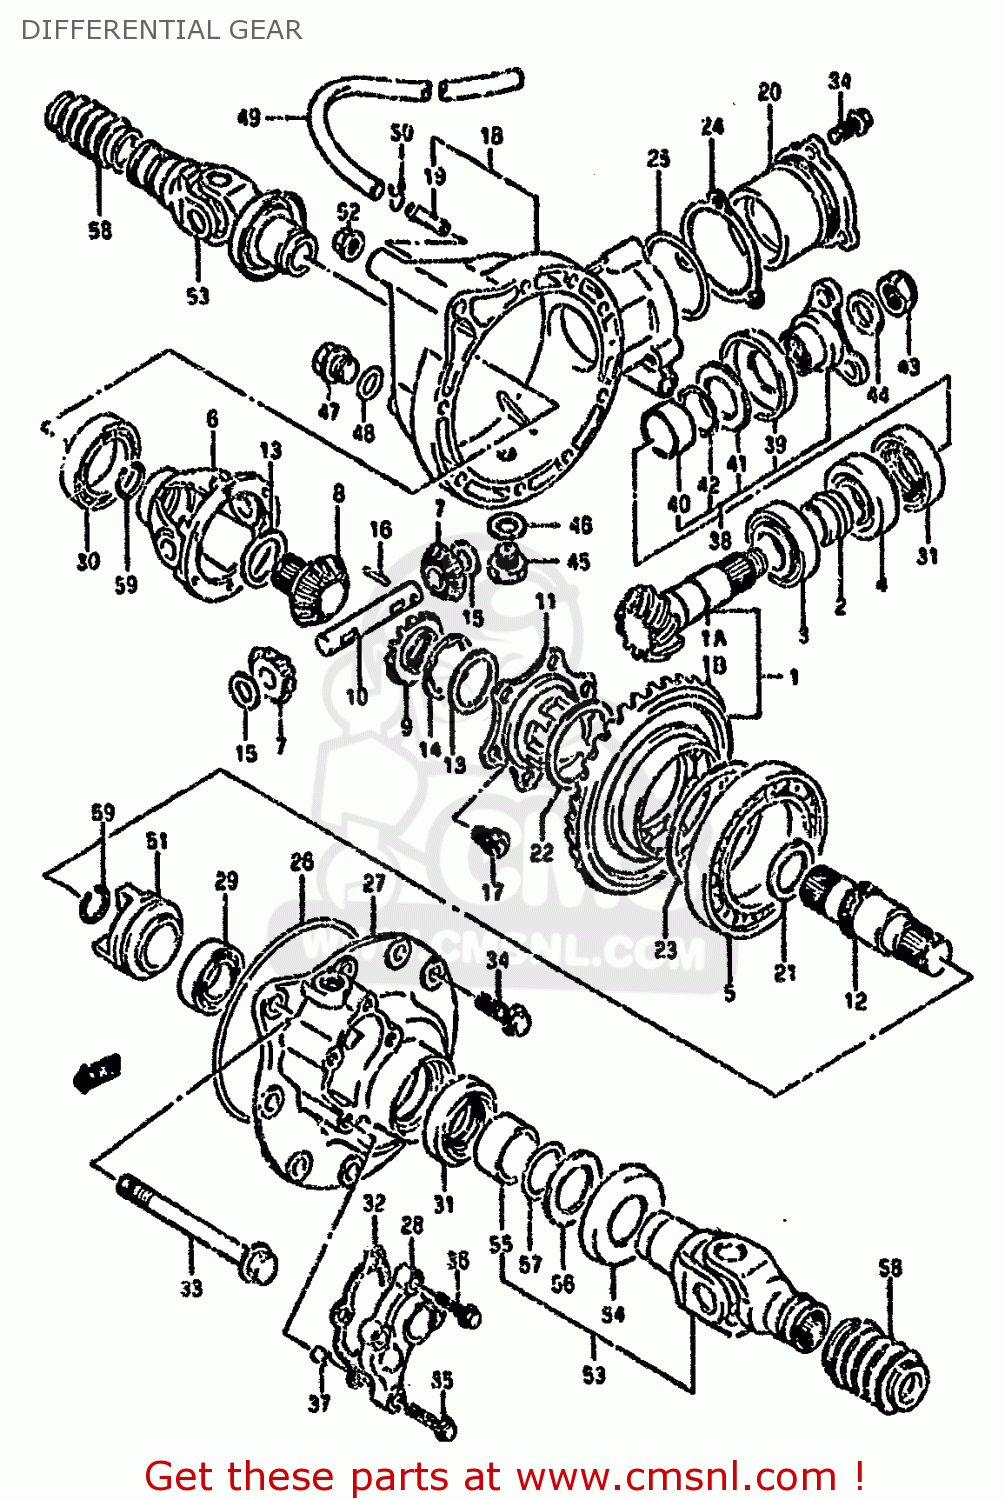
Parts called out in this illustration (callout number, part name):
1	GEAR SET,FINAL BEVEL
1A	GEAR,FINAL DRIVE BEVEL
1B	GEAR,FR DRIVEN BEVEL
2	SPACER(25.3X28X28)
3	BEARING(25X52X19.25)
4	BEARING(25X52X16.25)
5	BEARING(70X110X13)
6	CASE,FR DIFFERENTIAL
7	PINION,DIFFERENTIAL SIDE
8	GEAR,FR DIFFERENTIAL
9	GEAR,RR DIFF
10	SHAFT,PINION
11	HUB,FR DRIVEN BEVEL GEAR
12	SHAFT,FRONT DRIVEN OUTPUT
13	WASHER(29X40X1)
14	WASHER
15	WASHER(13.3X25X0.85)
16	PIN(6X30)
17	BOLT
18	HOUSING,FRONT DIFFERENTIAL GEAR
19	UNION
20	HOUSING,FR DRIVE BEVEL GR
21	WASHER
22	SHIM,FRONT DRIVEN BEVEL GEAR
23	SHIM,DRIVEN GEAR BEARING T0.35
24	SHIM,FRONT DRIVE BEVEL HOUSING
25	O RING(D:2.4,ID:62.6)
26	O RING(D:2.4,ID:131.4)
27	CASE,FR DRIVEN GEAR BEARING
28	COVER,FRONT DRIVEN GEAR C
29	BEARING
30	BEARING(40X62X12)
31	SEAL,OIL(34X52X9)
32	GASKET,CASE COVER (NA)
33	BOLT(10X110)
34	BOLT
35	BOLT
36	BOLT
37	PIN
38	FLANGE,FRONT DRIVE BEVEL
39	WASHER
40	COLLAR,OUTPUT OIL SEAL
41	PLATE,OUTPUT YOKE OIL SEAL
42	O RING(D:1,ID:28)
43	NUT
44	WASHER(16X30X3)
45	PLUG
46	GASKET(14X19.2X2) (NAS)
47	PLUG
48	O RING(D:2.4,ID:16.8)
49	HOSE(7X10.2X2000)
50	CLIP
51	DOG,DIFF LOCK SLIDING
52	NUT
53	JOINT,FR OUTPUT
54	WASHER
55	COLLAR,OUTPUT OIL SEAL
56	PLATE,OUTPUT YOKE OIL SEAL
57	O RING(D:1,ID:28)
58	BOOT,PROPELLER SHAFT
59	RING
